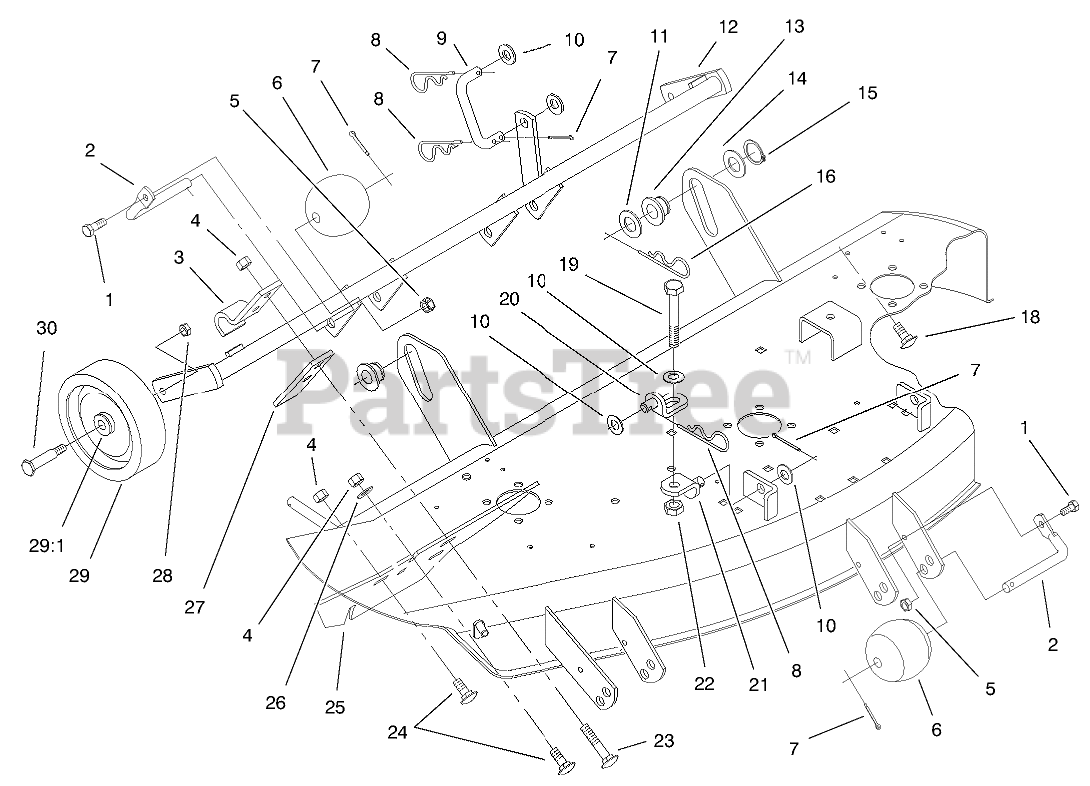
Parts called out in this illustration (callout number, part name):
1	SCREW-HH
2	Shaft-Roller
3	BRACKET-PIVOT
4	NUT-LOCK, NI
5	NUT-LOCK, NI
6	ROLLER
7	PIN-COTTER
8	PIN-COTTER, HAIR
9	LINK-REAR
10	WASHER-FLAT
11	WASHER-FLAT
12	SUPPORT-GAGE WHEEL
13	ROLLER-LIFT
14	WASHER
15	RING-RETAINING
16	PIN-HAIR
18	SCREW-CARR
19	SCREW-HH
20	BRACKET-LIFT, LOWER
21	BRACKET-LIFT, UPPER
22	NUT-JAM
23	SCREW-CARR
24	SCREW-CARR
25	PLATE-WEAR RH
26	WASHER-FLAT
28	NUT-HEX
29	WHEEL
29:1	BEARING
30	BOLT-SHOULDER
